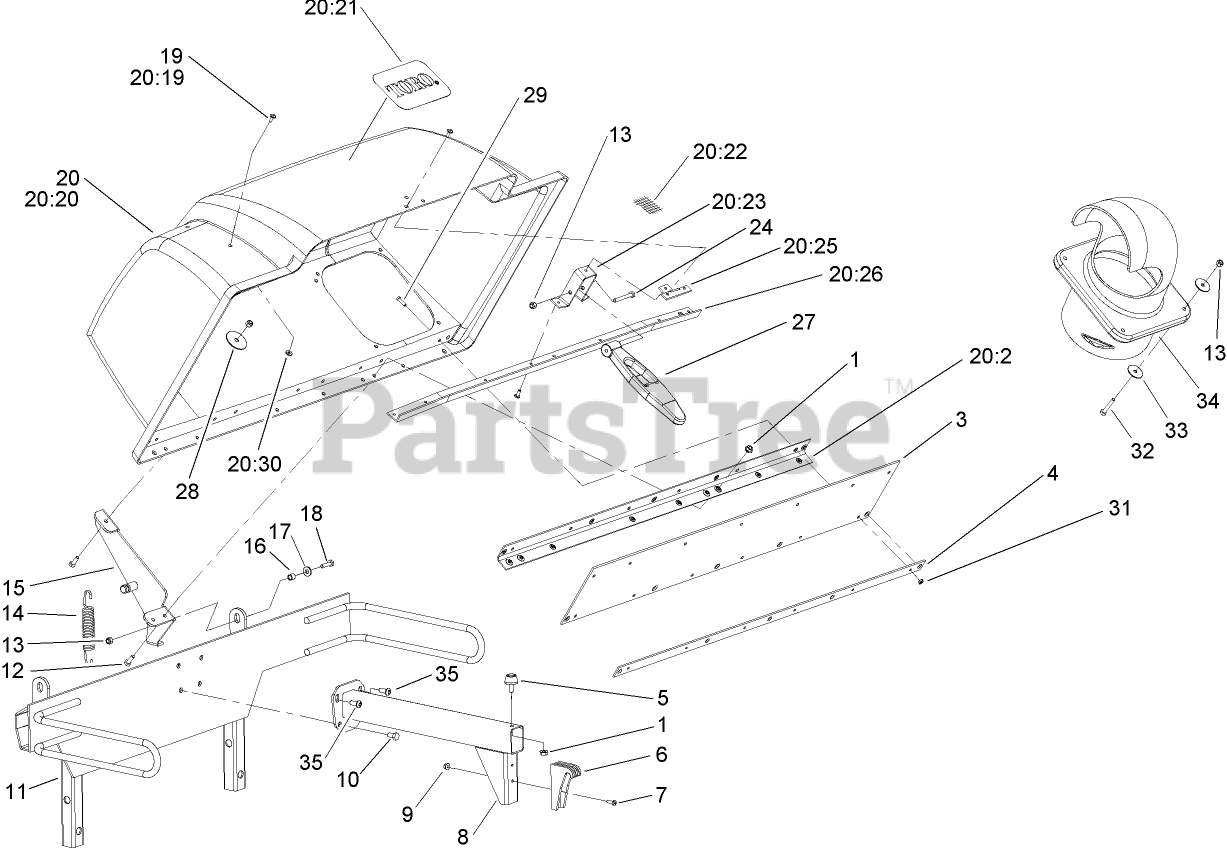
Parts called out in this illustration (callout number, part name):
1	NUT-HF
4	PLATE-BACKING
5	BUMPER
7	SCREW-PPH
8	SUPPORT-BAG
9	NUT-HF
10	SCREW-HH
11	BAGGER UPRIGHT ASM
12	SCREW-HH
13	NUT-LOCK, NI
14	SPRING-EXTENSION
15	HINGE ASM
16	SPACER
17	WASHER-FLAT
18	SCREW-HH
19	RIVET-BLIND
20	Hood ASM
20:2	STIFFENER-BAGGER, TOP
20:19	RIVET-BLIND
20:20	Top-Bagger
20:21	DECAL
20:22	SCREEN-BAGGER
20:23	ANCHOR-LATCH
20:25	REINFORCEMENT-LATCH
20:26	SUPPORT-SCREEN
20:30	WASHER-FLAT
24	SCREW-HH
28	WASHER
29	SCREW-HEAD, TRUSS
31	NUT-LOCK, SIDE
32	SCREW-HH
33	WASHER-FLAT
34	ADAPTER-TUBE, UPPER
35	SCREW-HSBH
